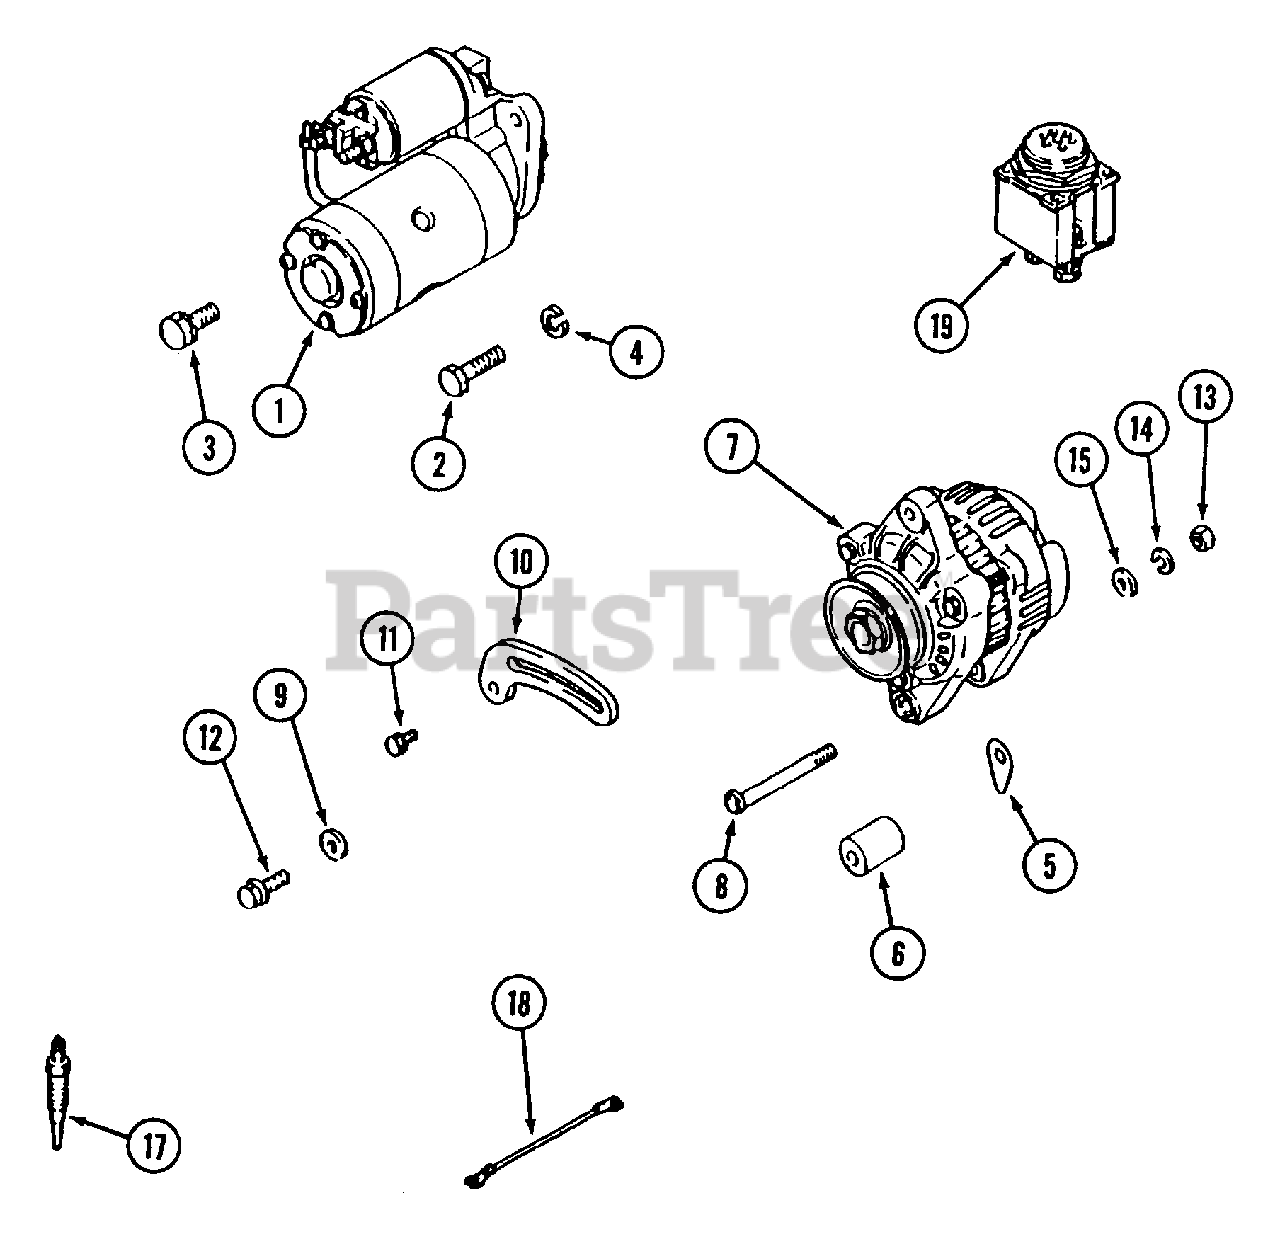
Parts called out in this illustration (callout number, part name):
1	Starter Ass'y.
2	Bolt, Starter
3	Bolt w/Washer
4	Washer, Lock
10	Brace, Generator
11	Bolt w/Washer
12	Bolt, Flange
14	Washer, Lock
15	Washer, Flat
17	Plug, Glow
18	Wire, Glow Plug Lead
19	Lamp, Glow
